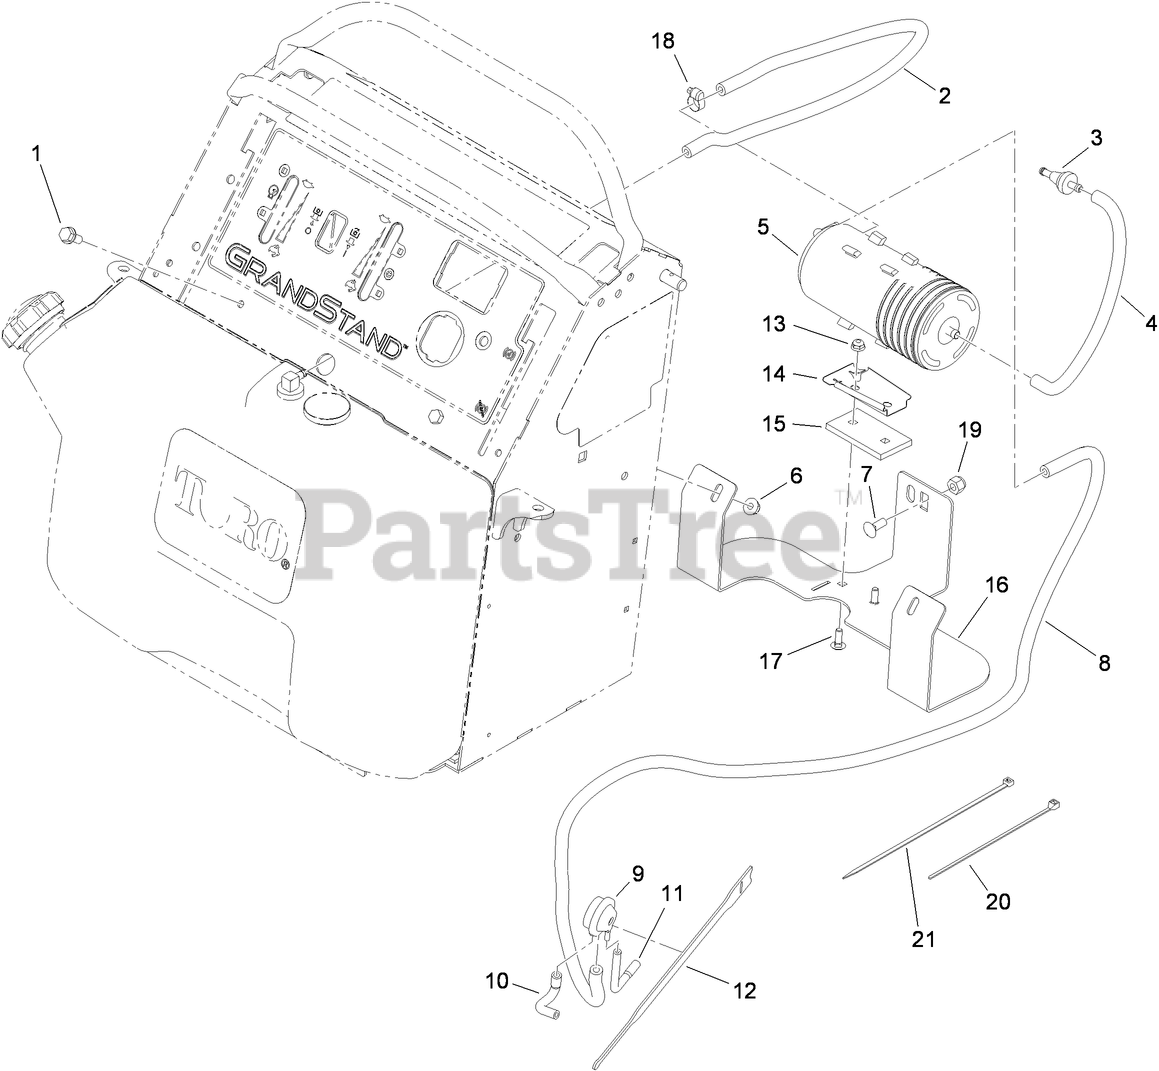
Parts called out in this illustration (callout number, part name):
1	SCREW-HWHTF
2	HOSE-FUEL
3	FILTER-FUEL
4	HOSE-FUEL
5	CANISTER-CARBON, 800CC
6	NUT-HF, NI
7	BOLT-CARR
8	HOSE-FUEL
9	VALVE-CONTROL, VACUUM
10	HOSE-VENT, FORMED
11	HOSE-VENT, FORMED
12	STRAP-VELCRO, CABLE TIE
13	NUT-HF
14	BRACKET-CANISTER, CARBON
15	PLATE-CANISTER, CARBON
16	TANK-SUPPORT
17	BOLT-CARR
18	CLAMP-WORM
19	NUT-LOCK, NI
20	TIE-CABLE
21	TIE-CABLE
